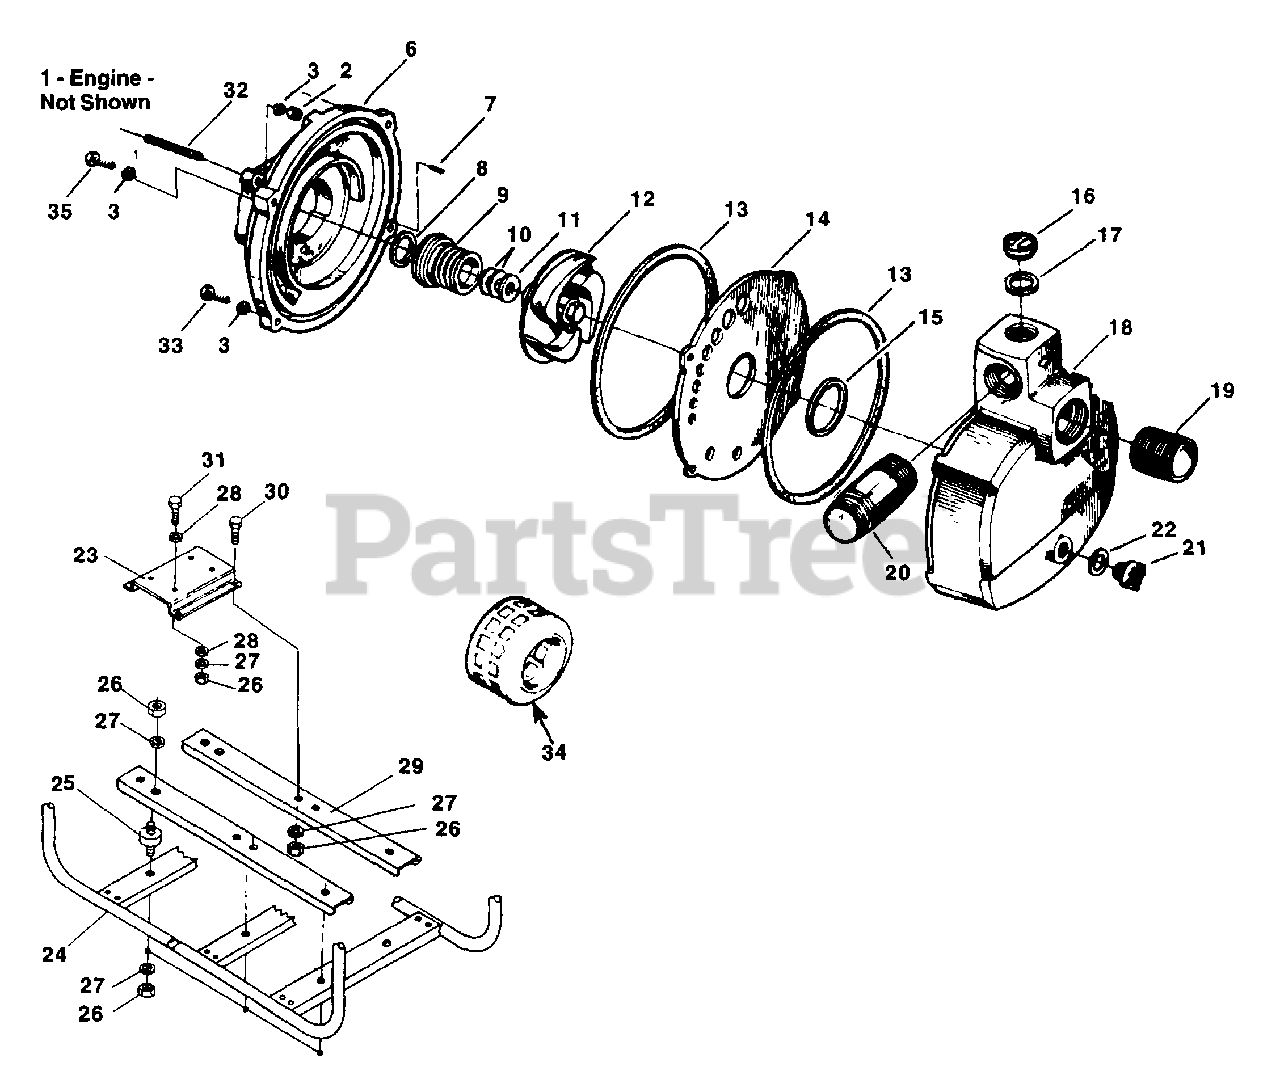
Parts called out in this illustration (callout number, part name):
2	NUT - 3/8-16
3	WASHER - Lock 3/8"
6	HOUSING - Impeller
7	PIN - Coiled spring
8	SLINGER
9	SEAL ASSEMBLY
10	SHIM - Seal (.010")
12	IMPELLER
13	GASKET - Large
14	PLATE - Wear
15	GASKET - Small
16	PLUG - Filler
18	HOUSING - End
19	NIPPLE - Suction
20	FITTING - Pipe (discharge)
21	PLUG - Drain
23	BRACKET - Engine
24	ROLL CAGE
25	ISOLATOR
26	NUT-Hex, 5/16-18
27	WASHER - Lock, 5/16"
28	WASHER - Flat, 5/16"
29	CHANNEL - Engine
30	SCREW - Hex Hd. 5/16-18 x 1
31	SCREW - Hex Hd. 5/16-18 x 1 3/4"
32	STUD
33	BOLT - 3/8-16 x 1 1/2"
34	STRAINER
35	SCREW - Hex Hd. 3/8-16 x 2"
